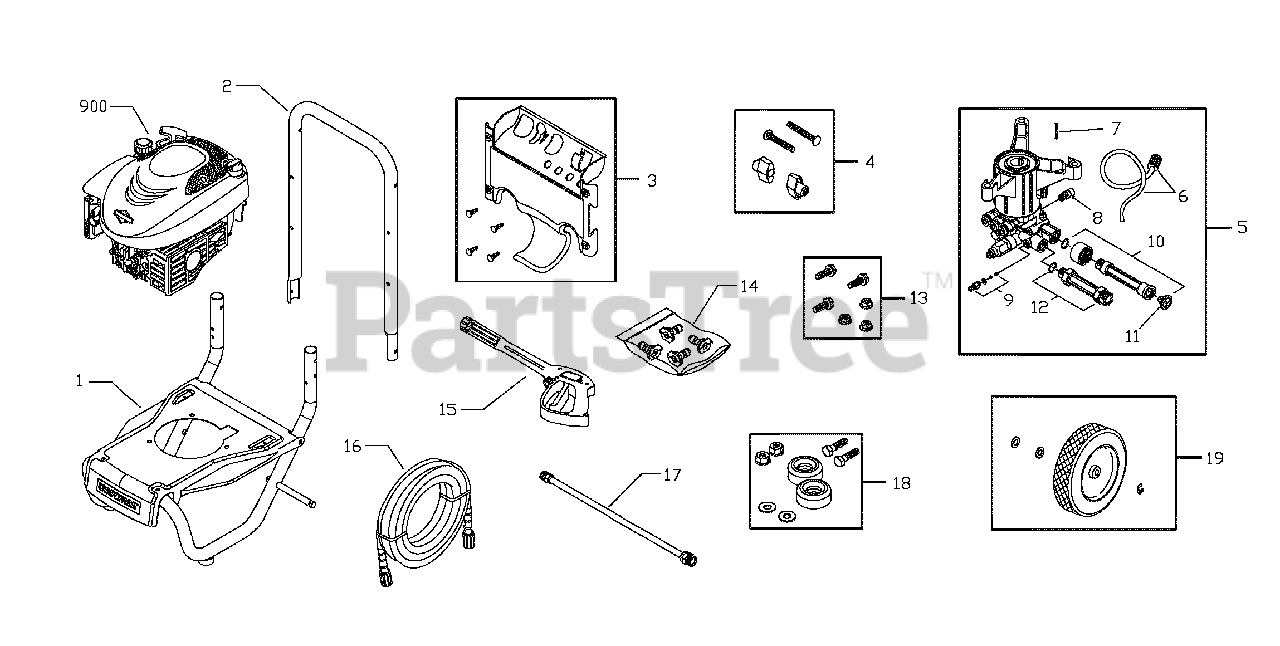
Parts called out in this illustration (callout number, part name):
2	HANDLE
4	KIT, Hardware Handle
5	PUMP
6	KIT, Chemical Hose
8	VALVE, Thermal Relief
9	KIT, Chemical Injection
10	KIT, Water Inlet
11	FILTER, Garden Hose
13	KIT, Hardware Pump Mounting
14	KIT, QC Nozzles
15	GUN
16	HOSE
17	EXTENSION, QC
18	KIT, Vibration Mount
900	*ENGINE
